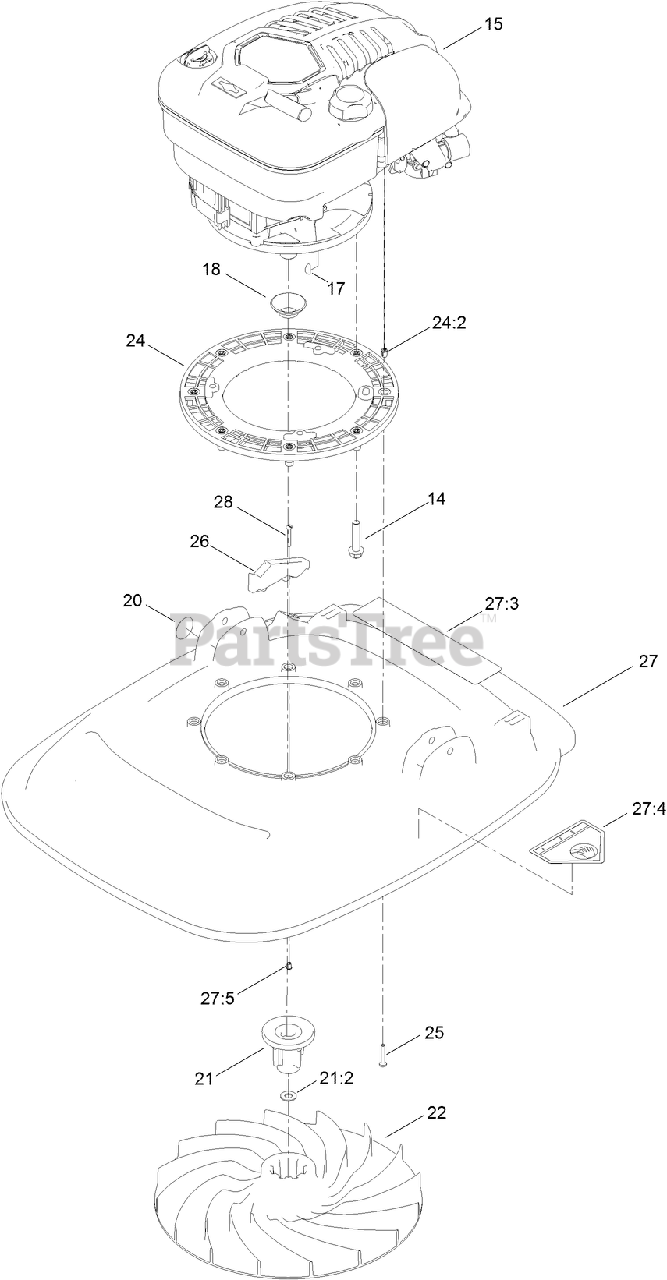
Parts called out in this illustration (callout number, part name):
14	SCREW-TAPTITE
15	ENGINE-HONDA
17	KEY-WOODRUFF
18	PROTECTOR-SEAL, OIL
20	DECAL
21	DRIVE AND SPACER ASM
21:2	WASHER-PLAIN
22	IMPELLER
24	FRAME-ENGINE
24:2	INSERT-BRASS
25	SET-SCREW
26	BRACKET
27	DECK ASM
27:3	DECAL-WARNING
27:4	DECAL-DANGER
27:5	INSERT
28	SCREW
